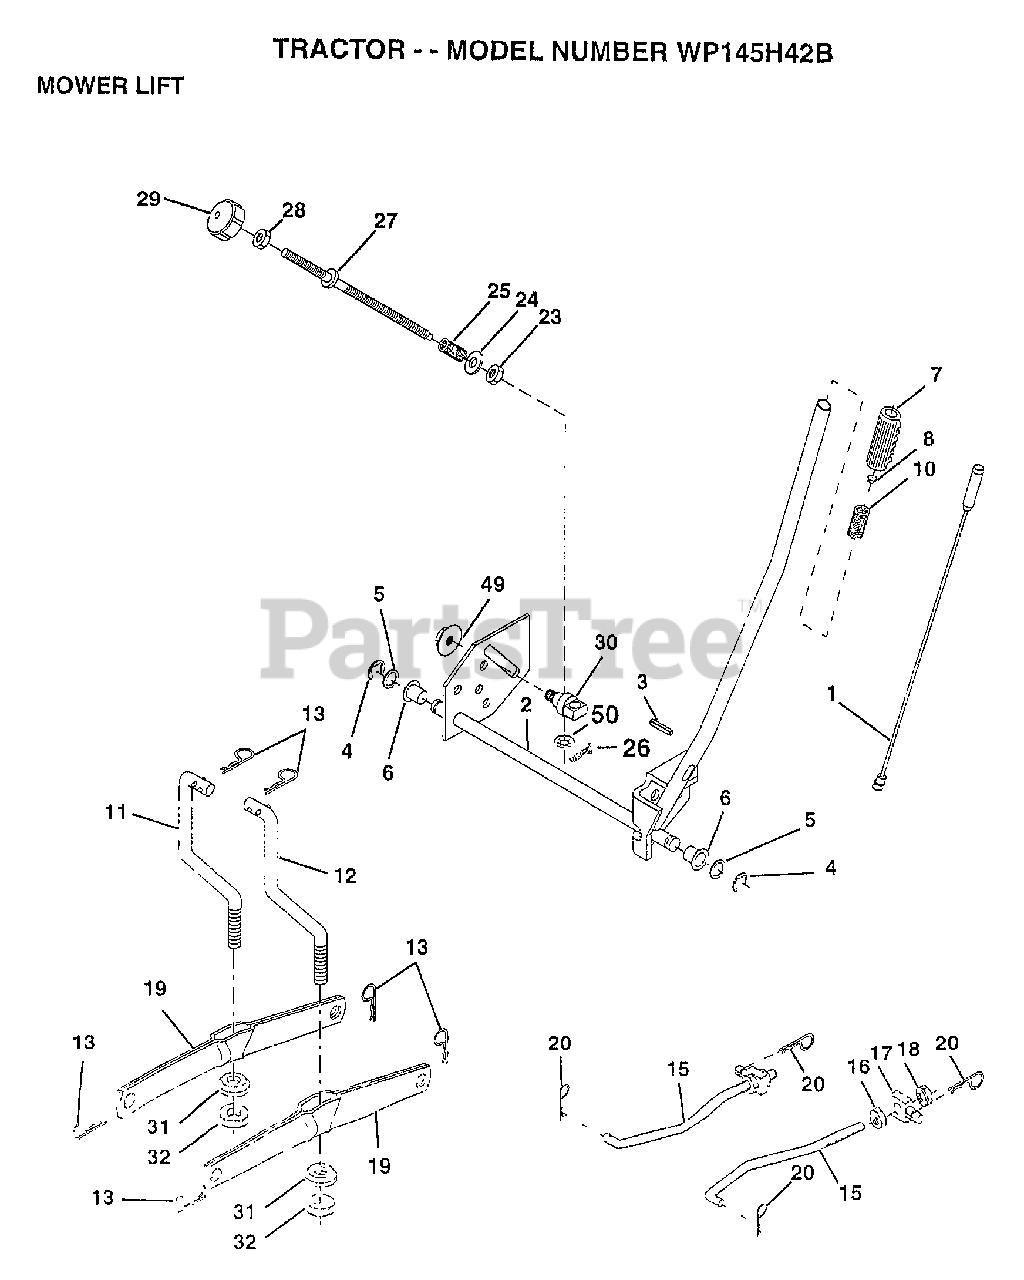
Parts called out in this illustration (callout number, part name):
1	WIRE.ASM.INNER
2	SHAFT.ASM.LIFT.RH
3	PIN GROOVE
5	WASHER
6	NYLON BEARING
7	GRIP
8	CONFLICT W/PART #
15	LINK.FRONT
16	NUT
17	TRUNION
18	NUT.LK.W/WSH.1/2.
19	ARM SUSP REAR
20	RETAINER.SPRING
23	NUT T
24	WASHER
25	SPRING.COMP.INF.H
27	ROD.ADJ.LIFT
28	NUT
29	KNOB INF 3/8-16
30	TRUNNION
31	BEARING PVT LH
32	NUT.CROWNLOCK.3/8
49	NUT.HXFLG.LOCK.
50	NUT PUSH M
